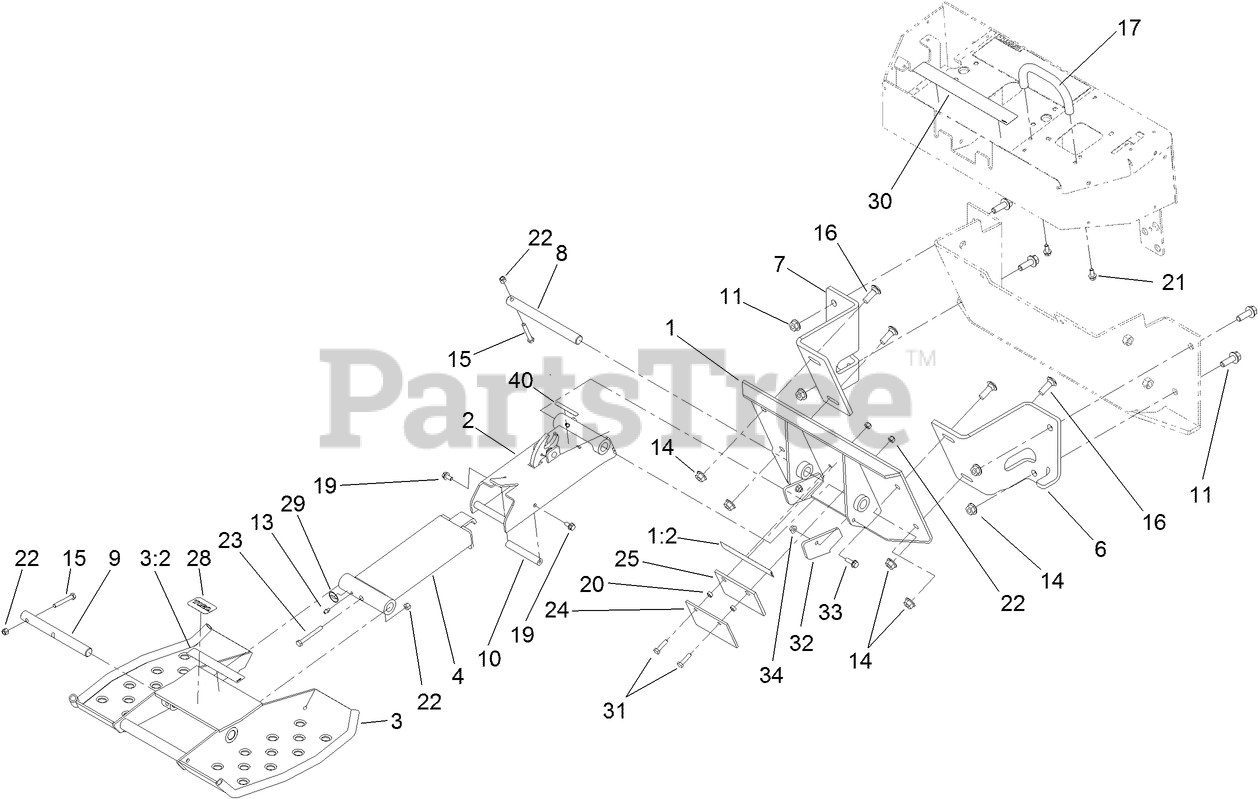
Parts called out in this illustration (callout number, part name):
1	SULKY MOUNTING PLATE ASM
1:2	DECAL-POINT, PINCH
2	LINKAGE ASM
3	PLATFORM ASM
3:2	DECAL-POINT, PINCH
4	SLIDE ASM, WELDED
6	PLATE-MTG, TX PLATFORM, RH
7	PLATE-MTG, TX PLATFORM-LH
8	PIN-UPPER
9	PIN-LOWER V
10	ROD-CLAMP
11	SCREW-HHF
13	FITTING-GREASE
14	NUT-HHF
15	SCREW-HH
16	SCREW-CARR
17	BAR-REFERENCE
19	SCREW-HHF
20	SPACER
21	SCREW-HHF
22	NUT-LOCK, NI
23	SCREW-HH
24	PLATE-PUSH
25	PAD-RUBBER
28	DECAL
29	DECAL-GREASE
30	DECAL-WARNING/INSTRUCTIONAL
31	SCREW-HH
32	PLATE-BUMPER
33	SCREW-HHF
34	NUT-HF
40	DECAL-WARNING
